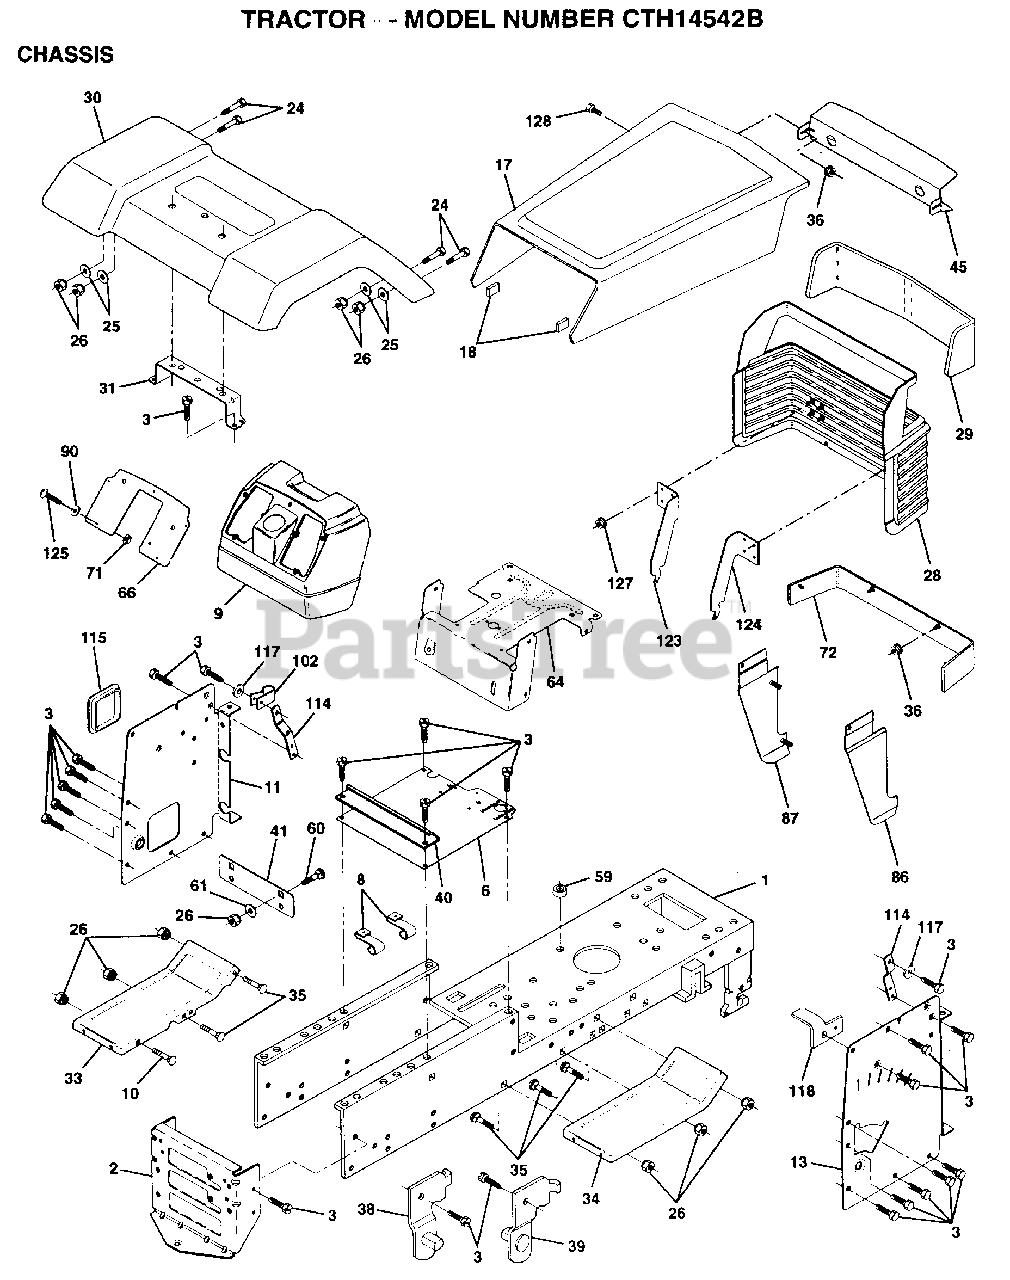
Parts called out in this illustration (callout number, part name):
1	CHASSIS.WLD.11GA
3	SCREW
8	"CLIP,INSULATOR"
9	DASH.PLASTIC.BLK
11	PANEL.DASH.LH.
13	PANEL.DASH.RH.
17	HOOD/GRILLE ASM
24	BOLT
25	WASHER
26	NUT
28	GRILLE ASM WELD
31	BRACKET SUPT FEND
33	FOOTREST.LH.LT/GT
34	FOOTREST.RH.LT/GT
35	BOLT
36	PAL NUT LT
38	BRACKET ASM LH
39	BRACKET ASM RH
40	SPACER FENDER LT
41	PLATE EXTEN FEND
60	BOLT
61	WASHER
64	DASH.LOWER.LT
66	PLATE DASH SILKSC
71	NUT HXKEP 1/4X20
72	STRAP FENDER ASM
86	PANEL SIDE RH ASM
87	PANEL SIDE LH ASM
90	WASHER PM
102	CLIP T
114	BRACKET.SUPT.DASH
115	COVER ACCESS
117	WASHER.SERRATED.
118	BRACKET.CLUTCH.MC
123	BRACKET.PICK.LH.
124	BRACKET.PICK.RH.
125	SCREW
127	PAL NUT
128	SCREW SPECIAL
